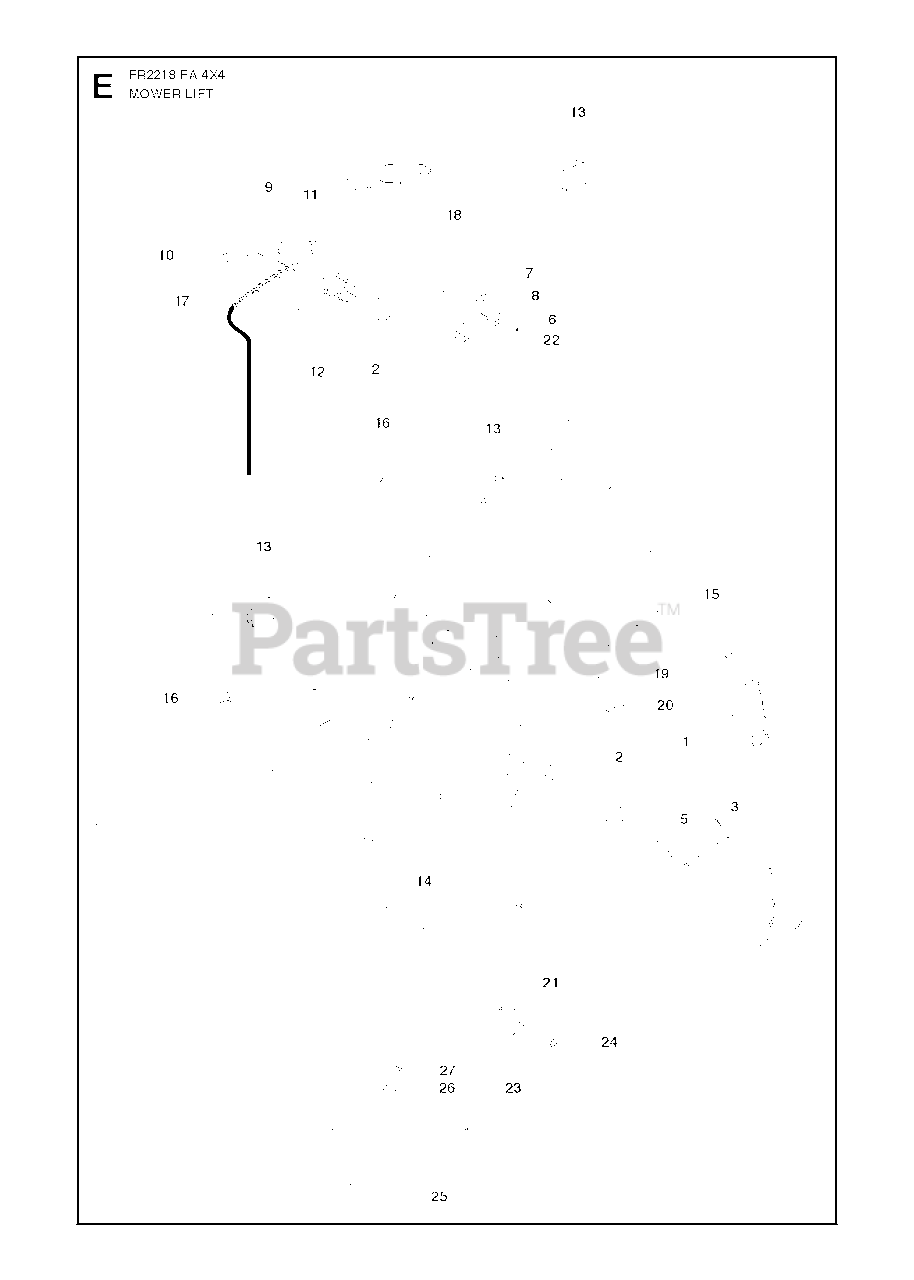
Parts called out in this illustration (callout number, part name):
1	LIFTING LEVER ASSY
2	BUSH
5	SPLIT PIN
6	LEVER CLUTCH
9	LIFTING ARM
16	LOCK RING
21	CONNECTION ROD
22	SPLIT PIN
24	RETAINING RING
25	CONNECTION ROD
27	SPLIT PIN
